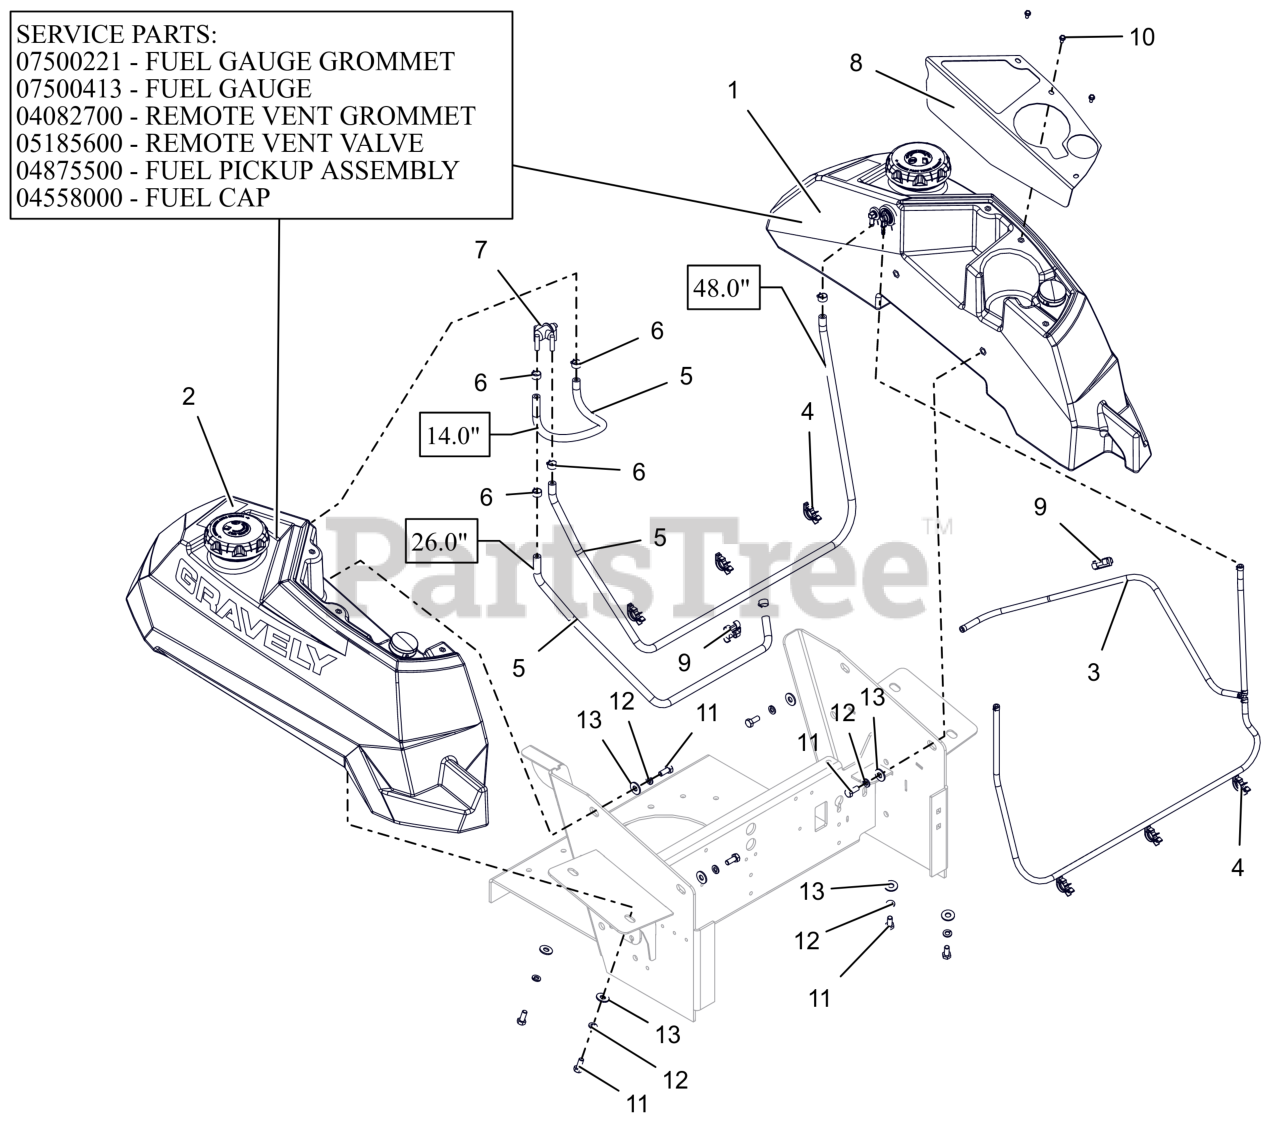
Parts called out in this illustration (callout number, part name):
1	ASM, LH - PT100 FUEL TANK
1	GROMMET, FUEL GAUGE
1	GAUGE, REMOTE SEALED FUEL
1	GROMMET, REMOTE VENT NITRILE
1	VALVE, COMBINATION VENT 3/16
1	ASSM,LRG TANK FUEL PICKUP LINE
1	CAP, FUEL VENTIN AUTOLOCK
2	ASM, RH - PT100 FUEL TANK
2	GROMMET, FUEL GAUGE
2	GAUGE, REMOTE SEALED FUEL
2	GROMMET, REMOTE VENT NITRILE
2	VALVE, COMBINATION VENT 3/16
2	ASSM,LRG TANK FUEL PICKUP LINE
2	CAP, FUEL VENTIN AUTOLOCK
3	ASM, VAPOR LINE
4	WIRE CLIP
5	HOSE, .25 LOW-PERM BULK GAS
6	CLAMP, FUEL LINE
7	VALVE, FUEL
8	PT100 CUPHOLDER PANEL - RED
9	CLIP, T, .38-.50
10	SCR-MCH 10-24X.38 HWHSTAINLESS
11	BLT,HEX .31-18X.75 G5 ZCC
12	WSHR,LK-REG .312X.078 ZCC
13	WSHR,FLT .375X.875X.083 ZCC
